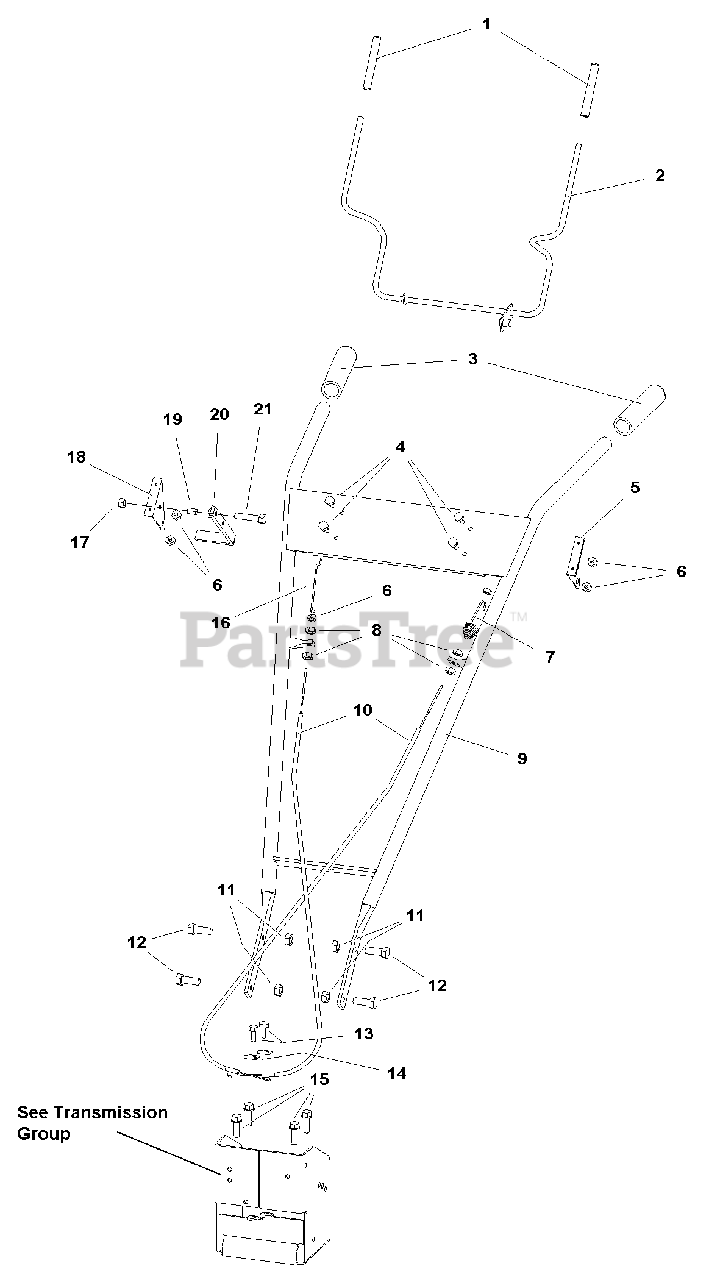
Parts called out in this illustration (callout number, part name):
1	HANDLE GRIP, Drive Control Lever
2	LEVER, Drive Control
3	HANDLE GRIP
4	SCREW, Pan Head Phillips, #10-24 x 1
5	BRACKET, Drive Control Lever LH
6	NUT, Hex Lock 10 - 24 w/Nylon Insert
7	SPRING, Forward Cable Adjustment
8	NUT, Hex Jam 5/16" - 24NF, 2B
9	HANDLE BAR ASSEMBLY
10	CABLE ASSEMBLY
11	NUT, Hex 3/8" - 16NC, 2B
12	CAPSCREW, Hex Head 3/8" - 16 x 1" G5
13	CAPSCREW, Hex Head M05, 0.80 x 15MM
15	BOLT, Hex Flange Head 5/16" - 18 x 3/4"
16	LINK, Reverse 5.5HP
17	NUT, Hex Flange 5/16" - 18 Two, Way Lock
18	BRACKET, Drive Control Lever RH
19	BUSHING, Pivot 5/16"
20	HANDLE, Reverse 5.5HP
21	CAPSCREW, Hex Head 5/16" - 18 x 1-1/4" G5
